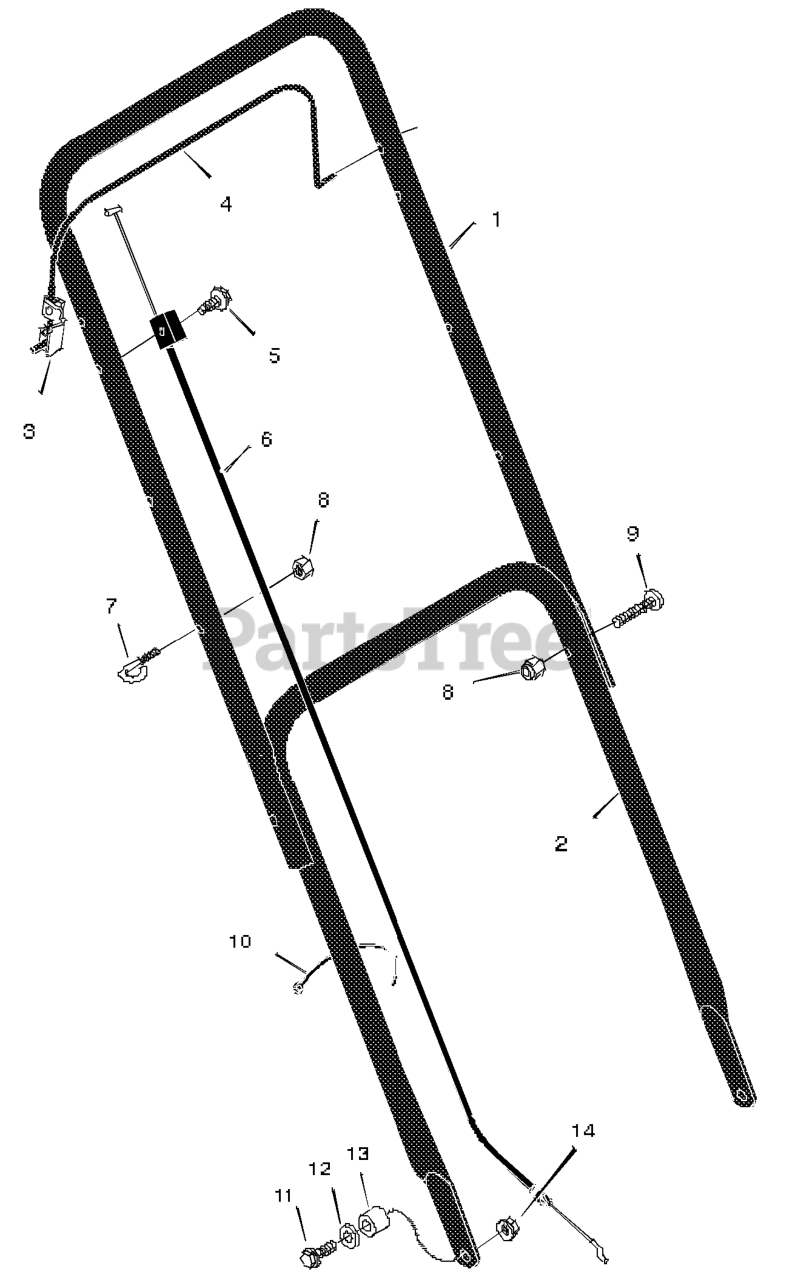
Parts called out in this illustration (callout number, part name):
1	Handle, Upper
2	Handle, Lower
3	Bracket, Stop Lever
4	Lever, Stop
6	Engine Stop Cable
7	GUIDE, ROPE
8	Locknut
10	Fastener, Cable
11	Bolt
14	Nut
